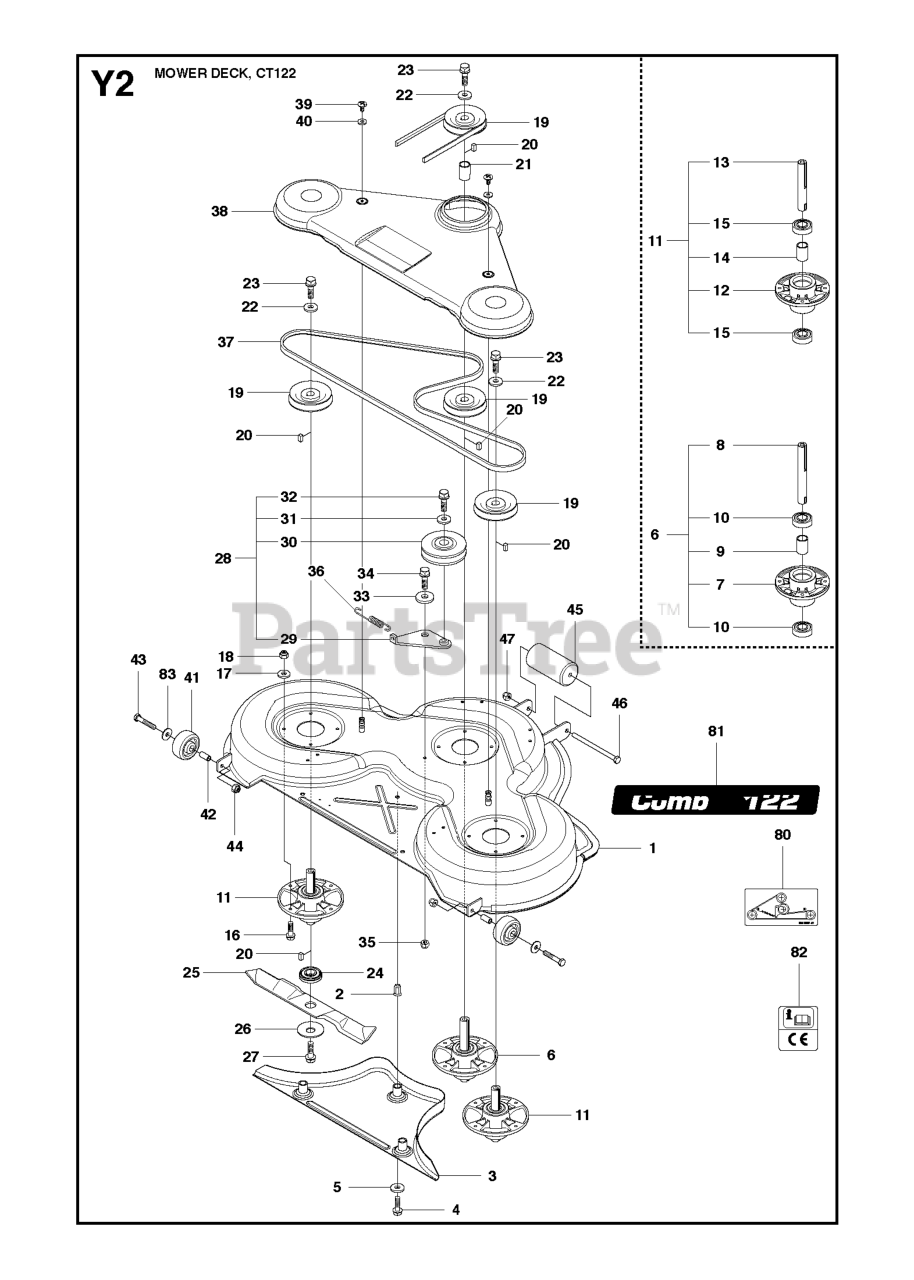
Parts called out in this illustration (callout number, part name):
4	SCREW
5	WASHER BRB 8.4X17
7	BEARING HOUSING
10	BALL BEARING
12	BEARING HOUSING
15	BALL BEARING
17	WASHER BRB 8.4X17
18	LOCKNUT M8
28	BELT TENSIONER ASSY
29	BELT TENSIONING ARM
33	WASHER
35	LOCKNUT M8
41	WHEEL
45	ROLLER
